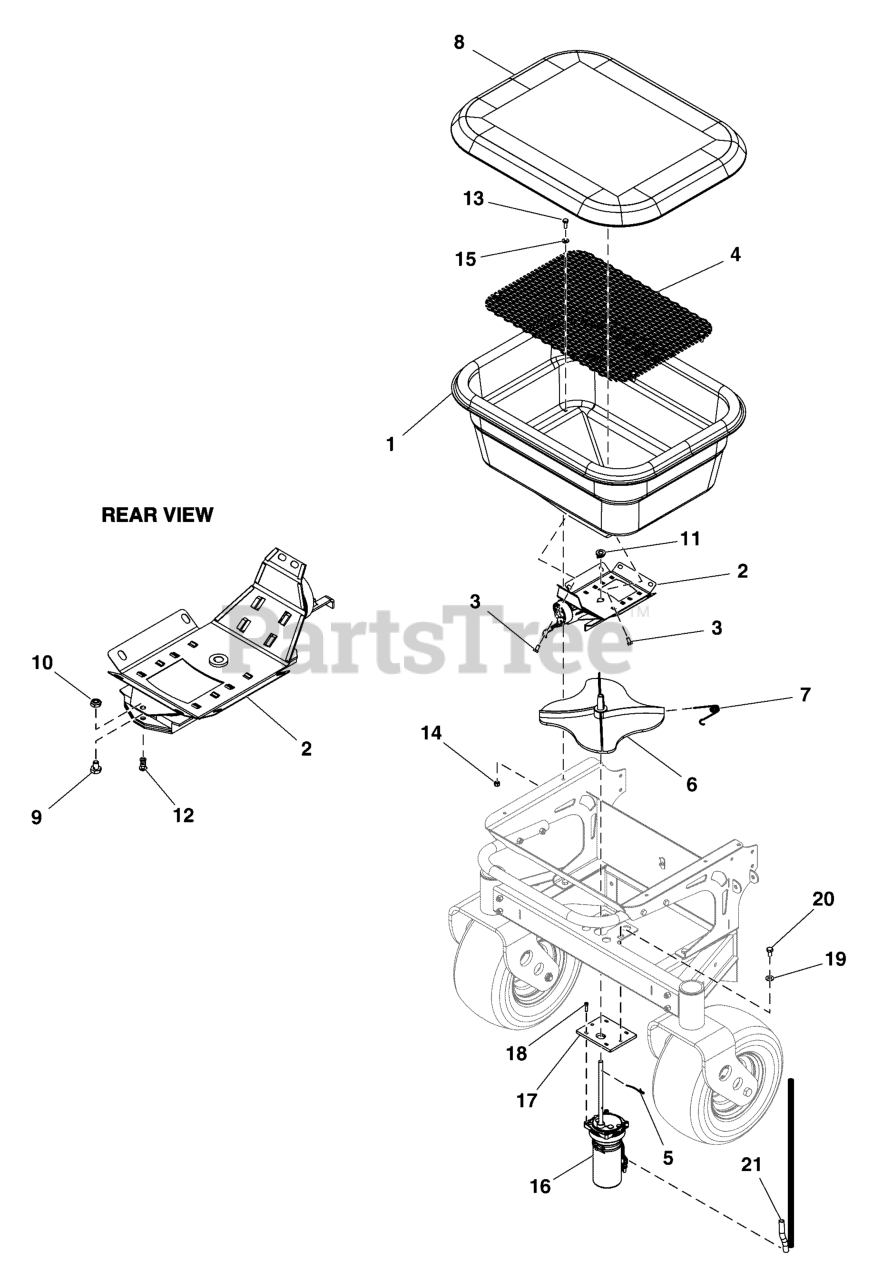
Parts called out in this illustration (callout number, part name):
1	HOPPER, 220 LBS
2	ASSEMBLY,GATE,COMPLET
3	SCR-CAP, HEX .250"-20 X .500" SS188
4	HOPPER, SCREEN, MODEL 220 LBS
5	CLIP, SPINNER AGITATOR
6	PLATE, SPREADER SPINNER
7	CLIP, SPREADER SPINNER
8	COVER, HOPPER, MODEL 220
9	SCR-CAP, HEX .250"-20 X .375" SS188 SPC
10	NUT-HEX-NYLK, .250"-20 TH SS188
11	BUSHING, HOPPER SPREADER
12	FITTING, SWIVEL ACCUWAY
13	SCR-CAP, HEX .250"-20 X .750" SS188
14	NUT-HEX-NYLK, .250"-20 SS188
15	WSHR-STL, FLT .281" X .625" X .050" IS SS188
16	SPINNER GEARMOTOR (E0118)
17	BRACKET, GEARMOTOR, SUPPORT
18	SCR-CAP SH, #10-32 X .750" SS188
19	WSHR-STL, FLT .343" X .750" X .050" SPC SS188
20	SCR-CAP, HEX .3125"-18 X .625" SS188
21	SPLIT LOOM, .350" ID 19.00" LONG
